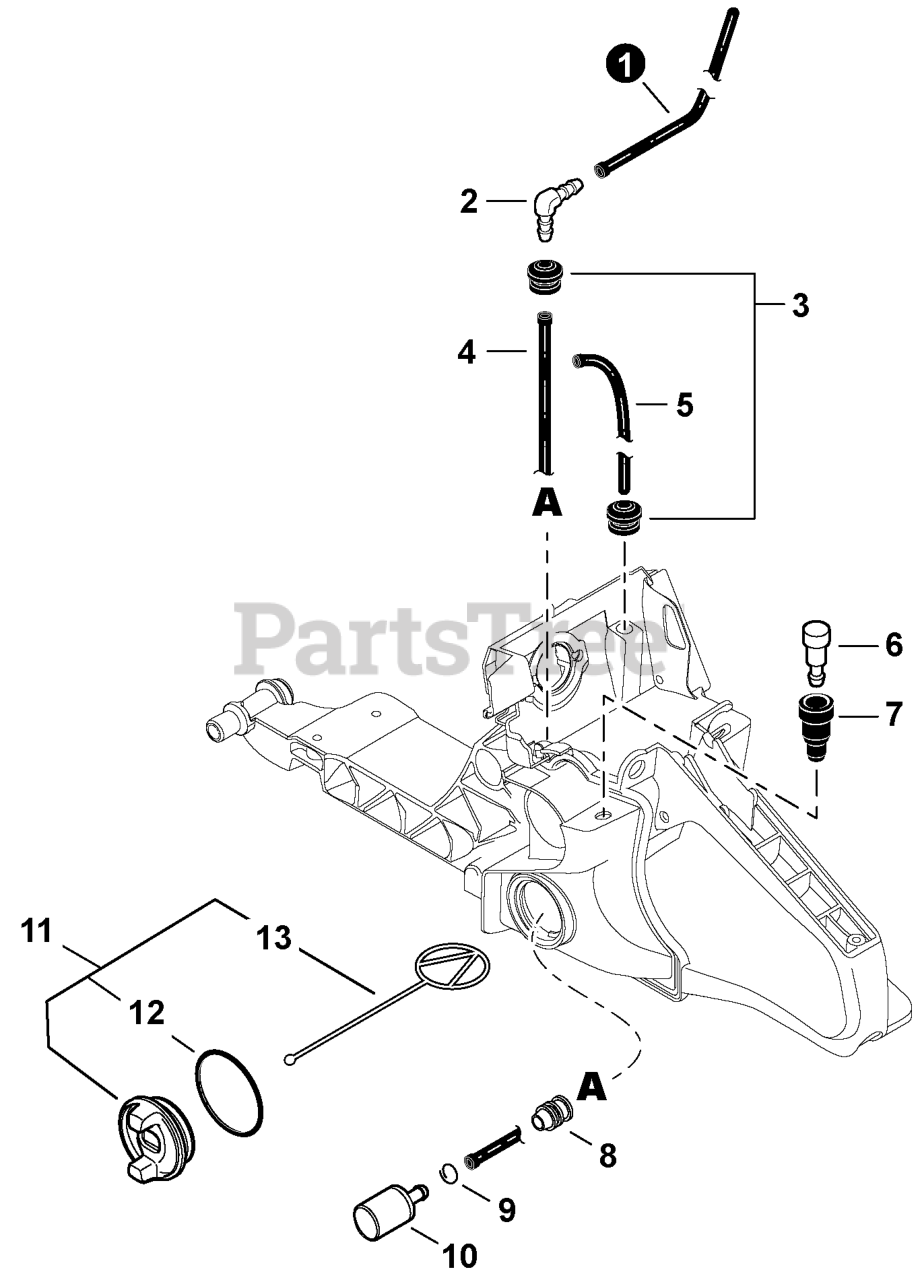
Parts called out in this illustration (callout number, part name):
1	PIPE, FUEL 3x6x135L
2	CONNECTOR, PIPE
4	PIPE, FUEL 3x5x120 BLACK
5	PIPE, IMPULSE 3x6(8)x160
6	VENT ASSY
7	GROMMET, VENT
10	FILTER, FUEL
11	CAP ASSY, FUEL
12	O-RING 29
13	CONNECTOR, CAP L= 60 MM
